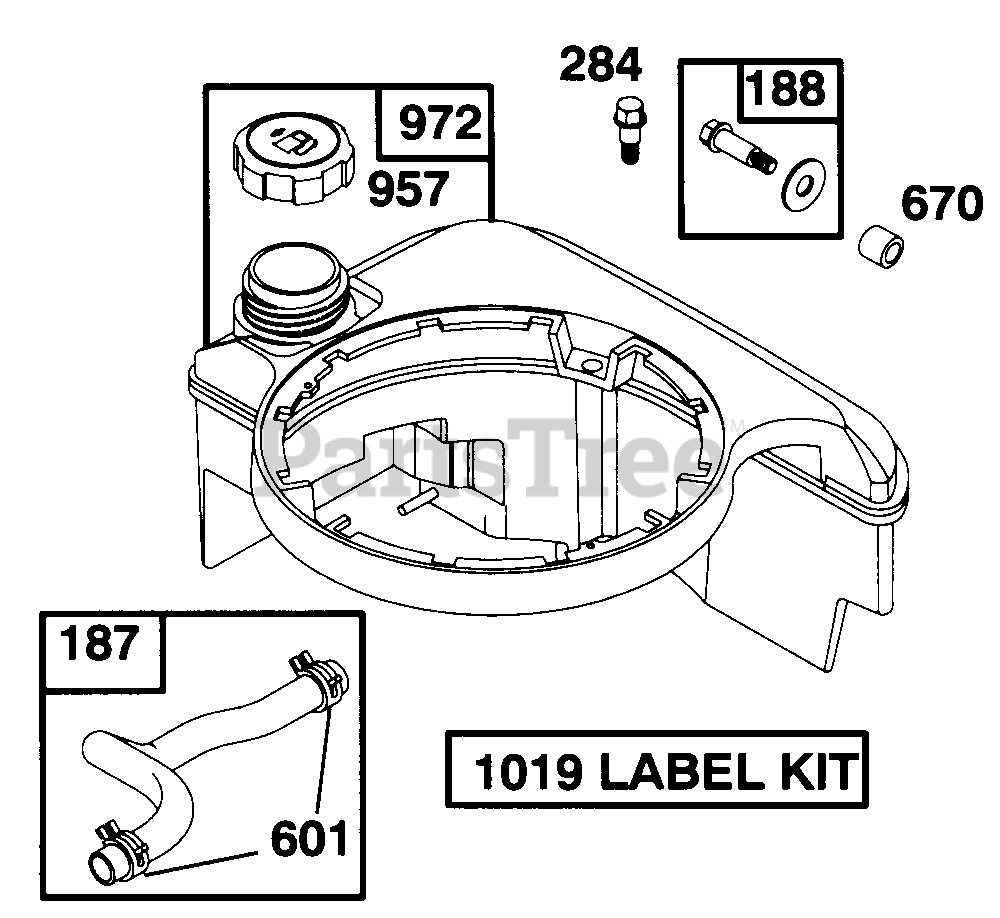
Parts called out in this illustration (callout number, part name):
187	Hose Assembly--Fuel
188	Screw--Hex Head
284	Screw--Hex Head
601	Clamp--Hose
670	Spacer--Fuel Tank
957	Cap Assembly--Fuel
972	Tank Assembly--Fuel
